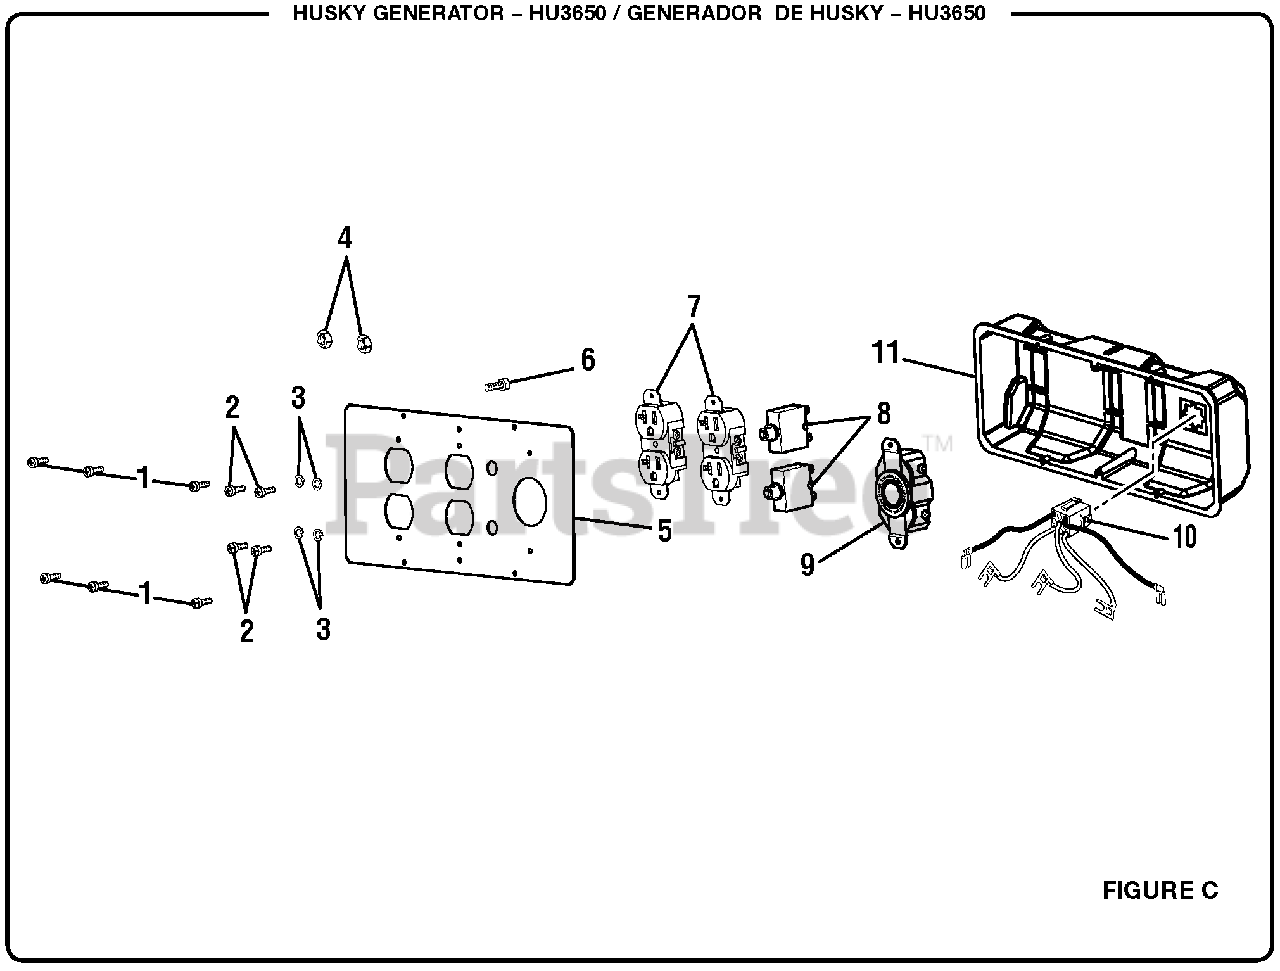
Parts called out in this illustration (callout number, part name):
1	Screw (6-20 x 3/8 in)
2	Screw (M3 x 6)
3	Lock Washer
4	Hex Nut (1/4-20)
5	Cover Plate
6	Screw (1/4-20 x 5/8 in, Hex Hd)
7	Duplex Receptacle (120 Volt)
8	Circuit Breaker (15 Amp, 125 Volt, HU3650)
9	Twist Lock Receptacle (120/240 Volt, 20 Amp)
10	Connector w/Leads
11	Rear Control Panel
